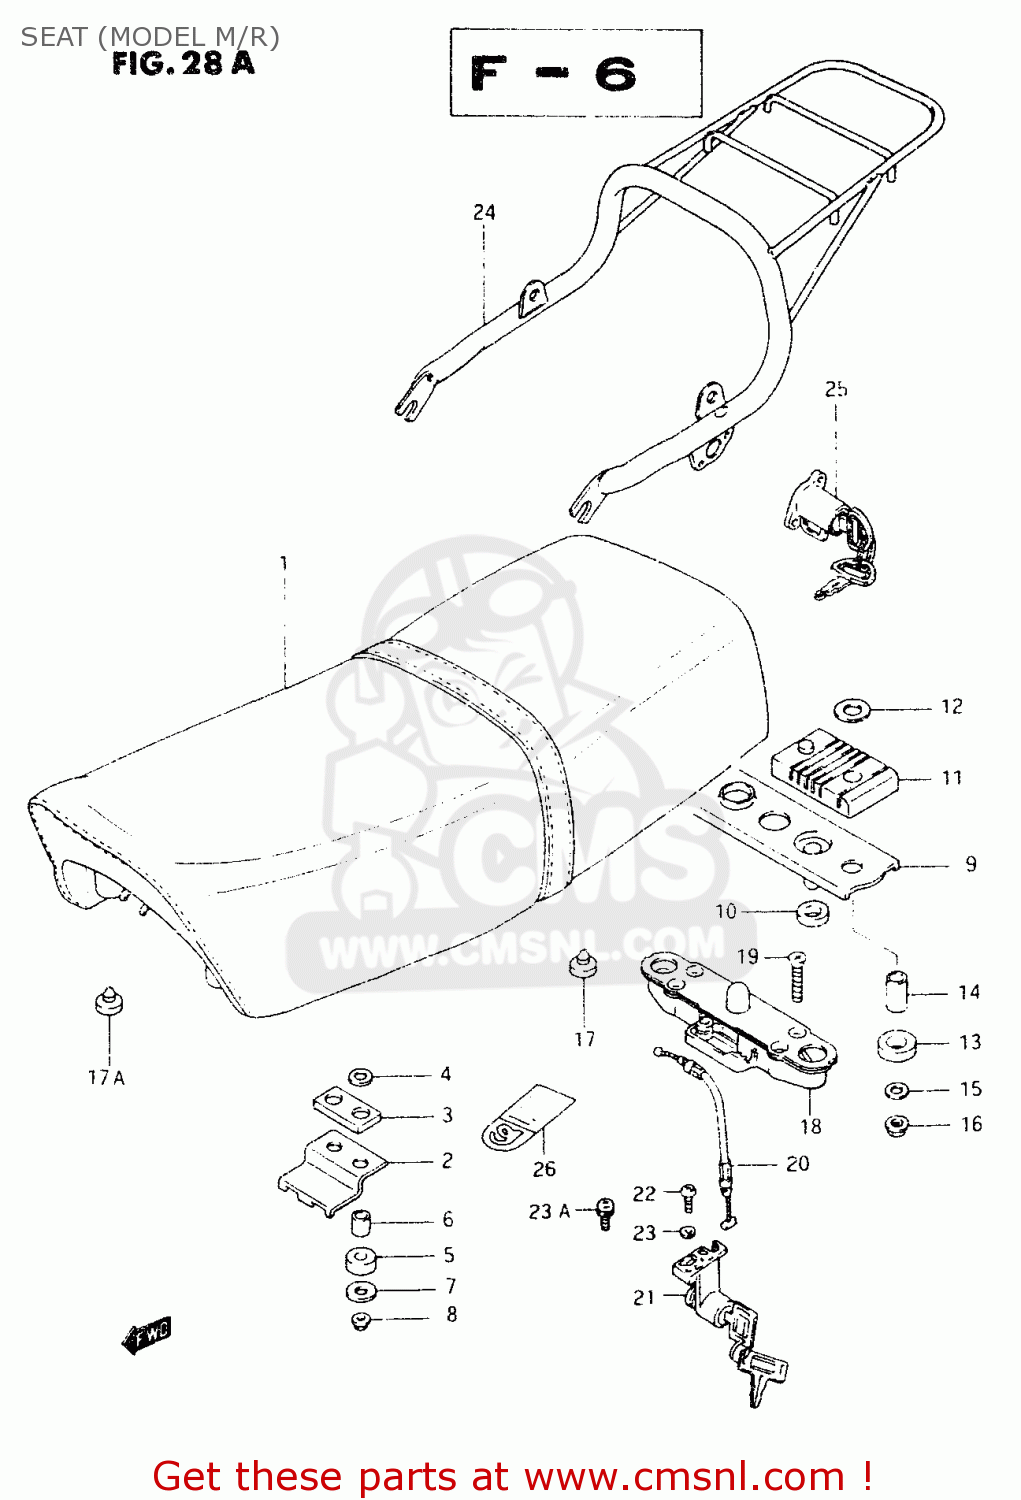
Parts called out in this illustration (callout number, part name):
1	SEAT SET
2	PLATE,SEAT HOOK FR
3	CUSHION,SEAT
4	WASHER
5	CUSHION
6	SPACER (6.1X8X12)
7	WASHER
8	NUT
9	PLATE,SEAT LOCK STRIKER
10	CUSHION
11	CUSHION, UPPER
12	WASHER
13	CUSHION,SEAT FR
14	SPACER,SEAT SUPPORT
15	WASHER
16	NUT
17	CUSHION
17A	CUSHION
18	LOCK ASSY,SEAT STRIKER
19	SCREW,6X30
20	CABLE,SEAT LOCK
21	LOCK SET,SEAT
22	SCREW
23	LOCK WASHER
23A	SCREW
24	CARRIER
25	LOCK SET,HELMET
26	LABEL,ASBESTOS WARNING
